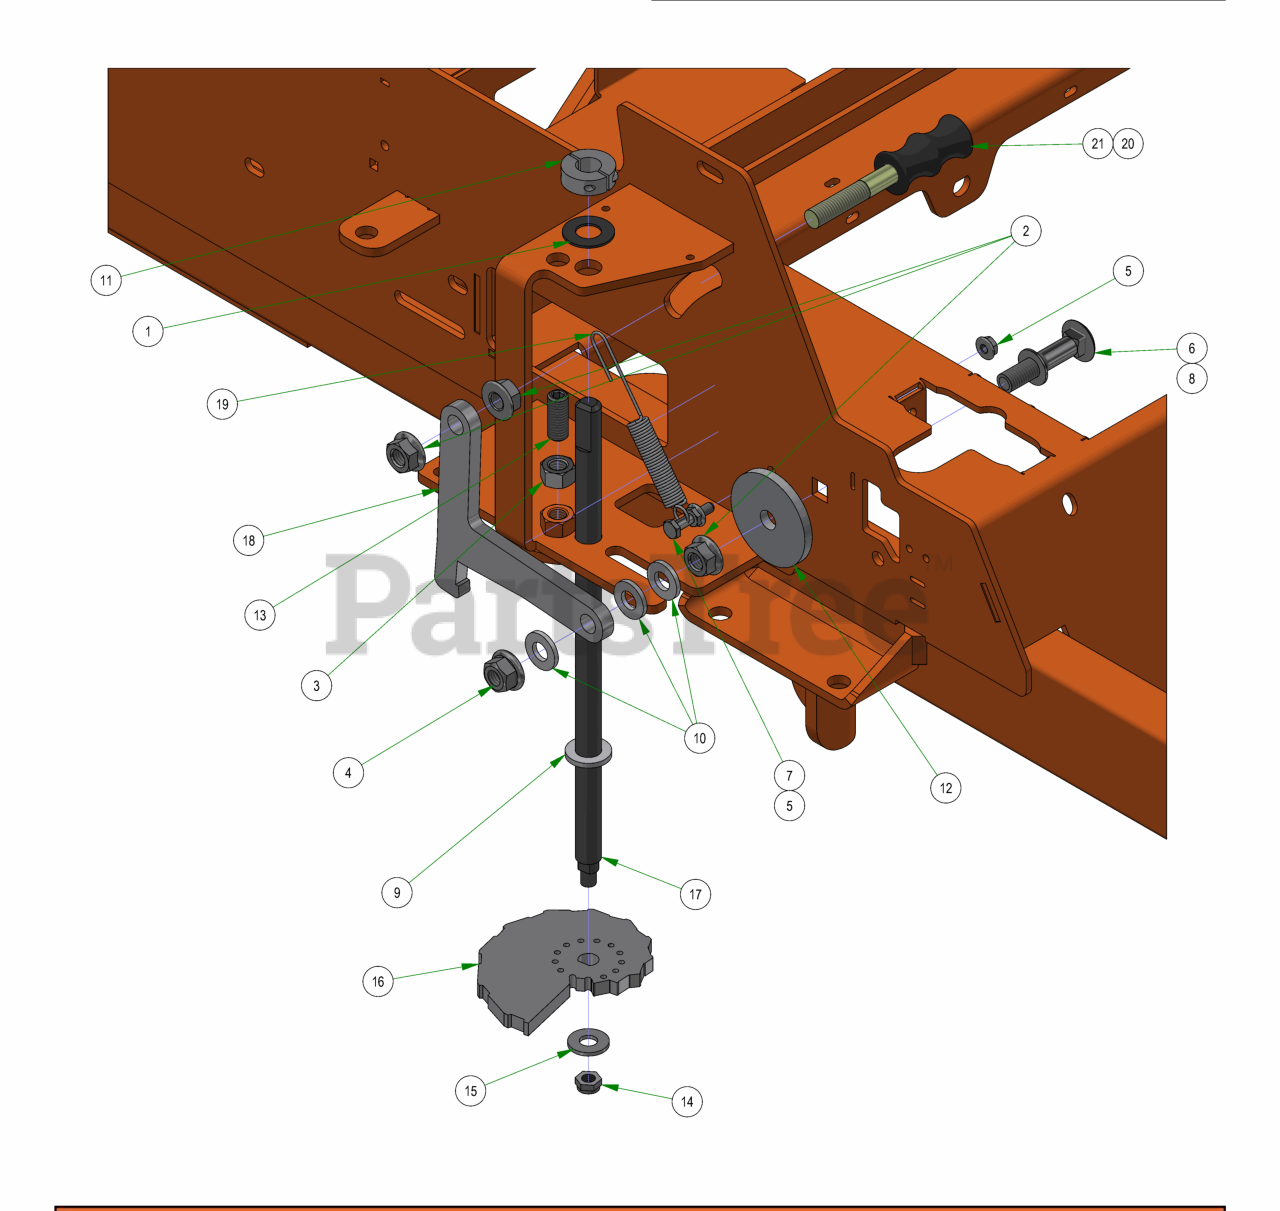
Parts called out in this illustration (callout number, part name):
1	.625 ID x 1.250 OD x .062 THK F/W Nylon
2	1/2-13 HEX SERRATED FLANGE NUT HARD/ZINC
3	1/2-13 HEX NUT ZINC
4	1/2-13 NYLON INSERT FLANGE LOCKNUT ZINC
5	1/4-20 HEX SERRATED FLANGE NUT HARD/ZINC
6	2 1/2 x 1/2 Carriage Bolt
7	1/4-20 X 1-1/4 HEX CAP SCREW (GR.5) ZINC
8	.517 SQ WDTH ID X .937 OD X .060 THICK F/W PHOS/OIL
9	.635 ID X 1.120 OD X .140 THICK FLAT WASHER NYLON
10	.505 ID X 1.000 OD X .125 THICK FLAT WASHER NYLON
11	5/8" Split Collar
12	MZ Deck Idler Spacer
13	Dial Rod Plunger
14	3/8-24 Nylon Insert jam locknut
15	3/8" Flat Washer
16	2019 Deck Height Cam
17	2019 Outlaw Gen2 Dial Rod
18	2019 Outlaw Deck Travel Lock
19	Brake Spring
20	Seat Bracket Pin
21	Travel Lock Rubber Grip
